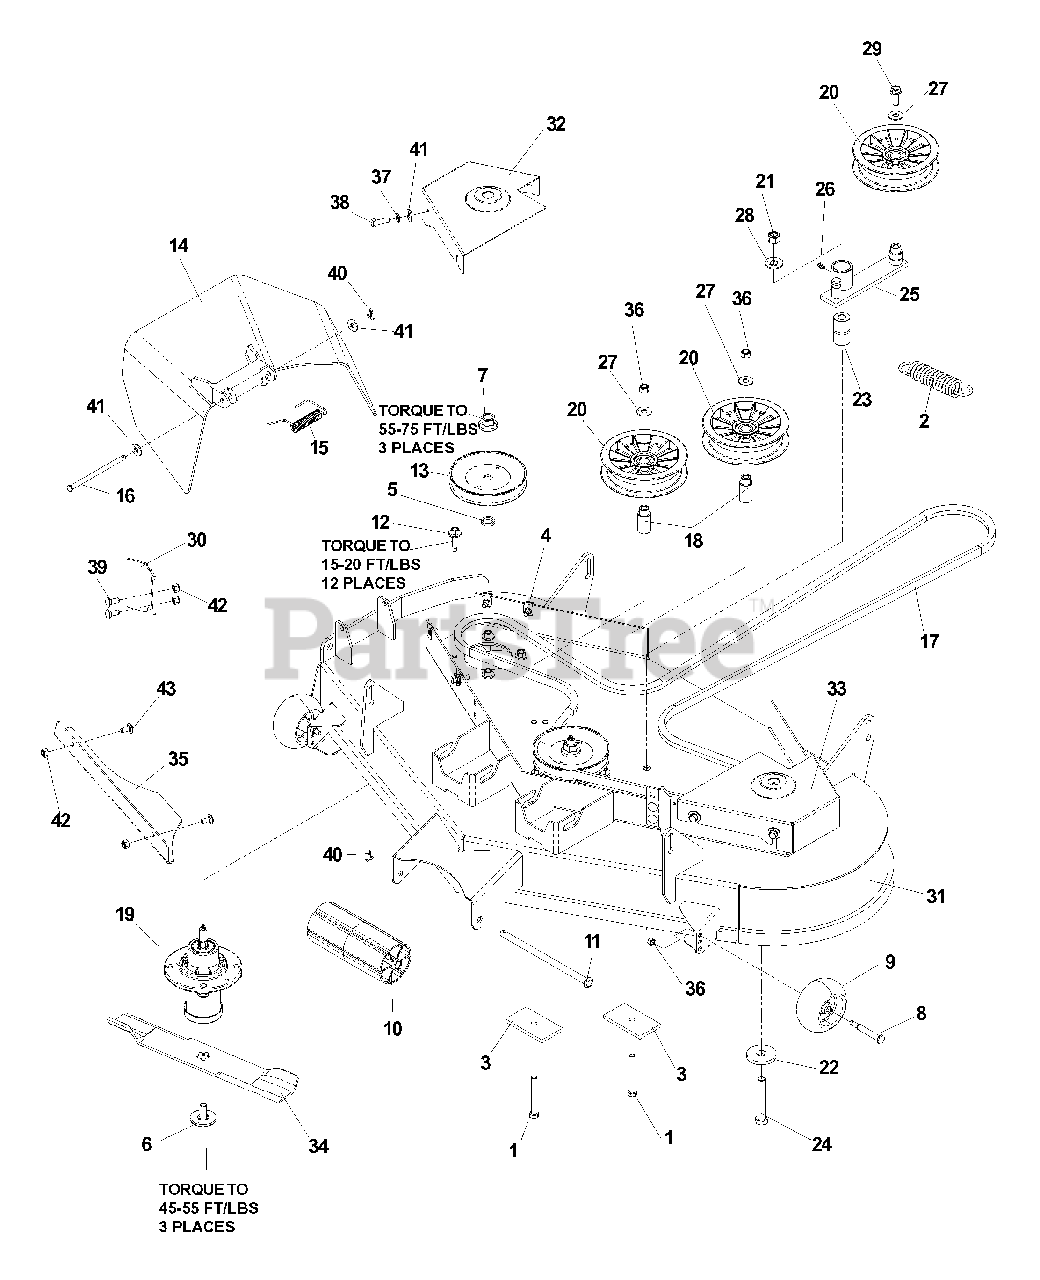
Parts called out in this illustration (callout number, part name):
1	HCS, 3/8-16, GR5
2	SPRING, EXTENSION
3	PAD
4	NUT, 5/16-18, RETAINING-U
5	WASHER, .675
6	BOLT, 7/16, SPEC
7	NUT, 9/16, TOP CENTERLOCK, GR5
8	SB, 1/2 X 2 5/8, SPEC
9	WHEEL, GAUGE
10	ROLLER, NOSE
11	ROD, ROLLER, NOSE, NARROW
12	SCREW, 5/16-18 X 1 3/8, WASH HD, SPEC
13	PULLEY, MANDREL
14	DISCHARGE CHUTE
15	SPRING, TORSION
16	PIN, CLEVIS, 5/16 DIA X 5.19
17	DECK BELT
18	IDLER BUSHING
19	HOUSING ASSEMBLY
20	IDLER PULLEY
21	NUT, 1/2-13, NYLOC
22	WASHER, .65
23	BUSHING, PIVOT
24	HCS, 1/2-13 X 3 1/4, GR5
26	ZERK, STRAIGHT, 1/4-28
27	WASHER, 3/8
28	WASHER, 9/16
29	HCS, 3/8-16 X 1, GR5, WHIZLK
31	48" DECK W/DECALS
32	BELT SHIELD W/DECAL, RIGHT
33	BELT SHIELD W/DECAL, LEFT
34	BLADE, 16 1/4"
35	CONFINEMENT PLATE
36	NUT, 3/8-16, NYLOC
37	WASHER, 5/16
38	HCS, 5/16-18 X 1, GR5
39	RHSNB, 5/16-18 X 3/4, GR5
40	PIN, COTTER, 1/8 X 3/4
41	WASHER, 5/16
42	NUT, 5/16-18, NYLOC
43	RHSNB, 5/16-18 X 5/8, GR5
